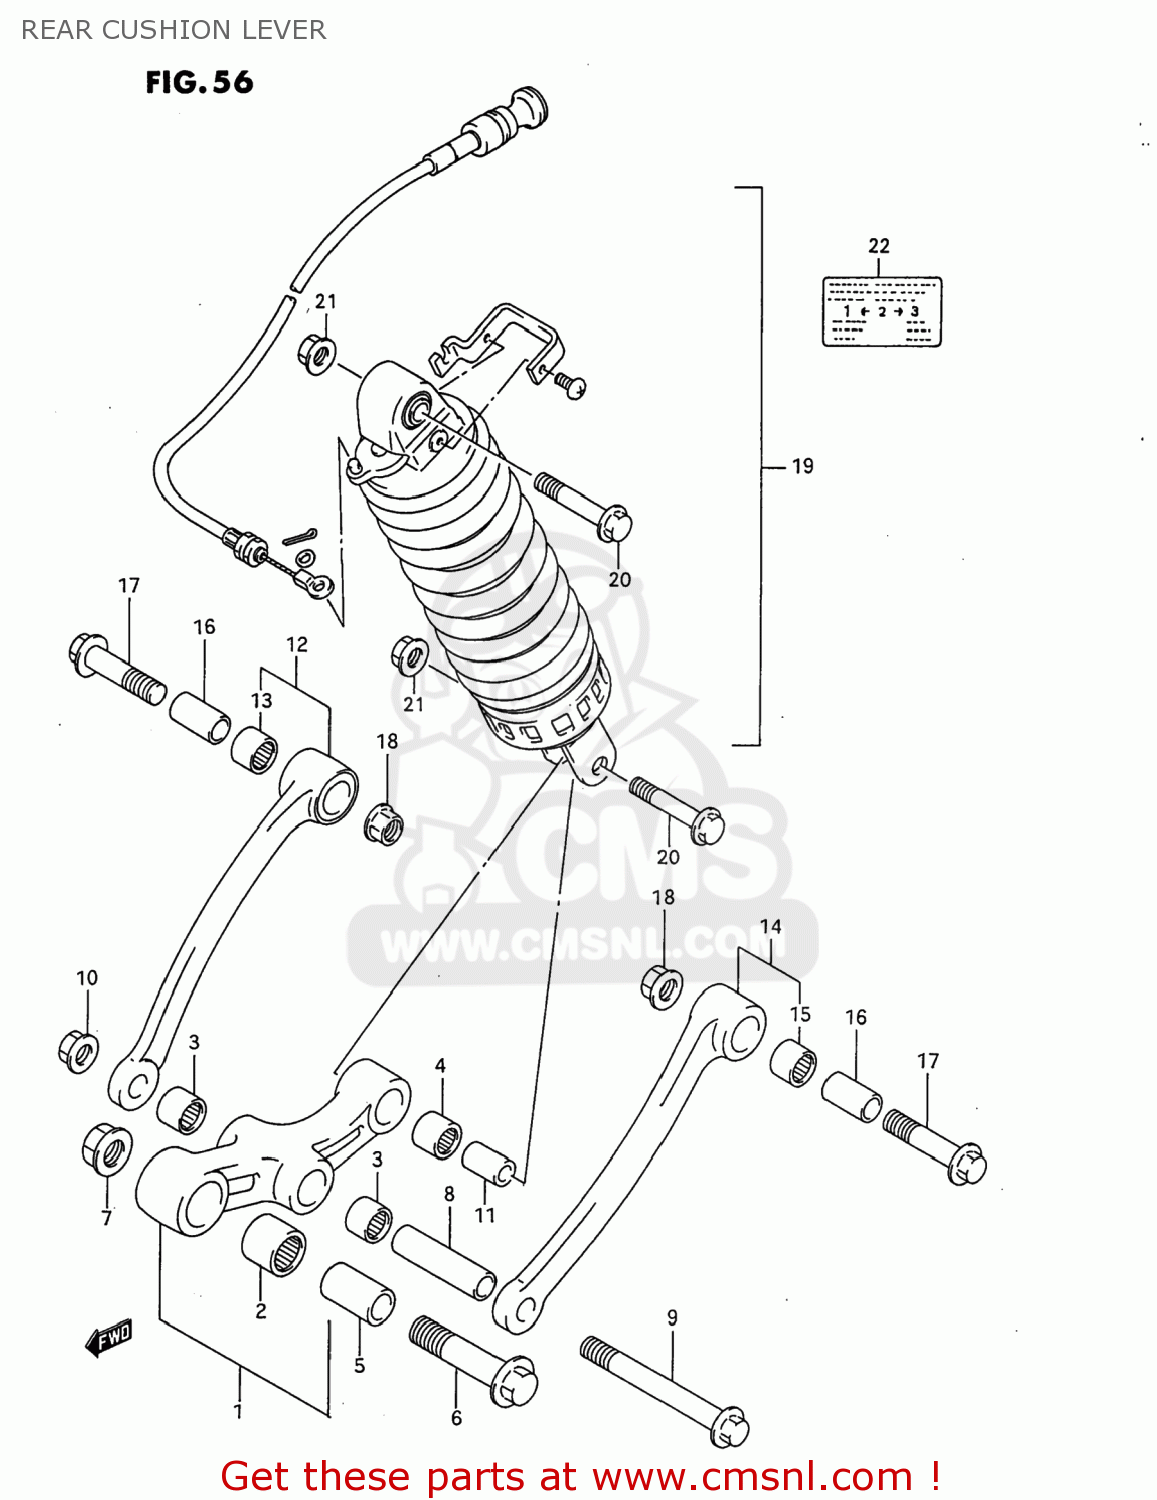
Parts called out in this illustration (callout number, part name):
1	LEVER SET,RR CUSHION
2	BEARING(20X27X30)
3	BEARING(17X24X25)
4	BEARING(17X24X26)
5	SPACER(14X20X34)
6	BOLT(14X62)
7	NUT 14MM
8	SPACER(12X17X60)
9	BOLT(12X96)
10	NUT 12MM
11	SPACER,RR CUSHION LEVER
12	ROD SET,REAR CUSHION,RIGHT
13	BEARING(17X24X26)
14	ROD SET,REAR CUSHION,LEFT
15	BEARING(17X24X26)
16	SPACER(12X17X29)
17	BOLT L:52
18	NUT 12MM
19	ABSORBER ASSY,RR SHOCK
20	BOLT(10X52)
21	NUT 10MM
22	LABEL (REAR SHOCK ABSORBER)
